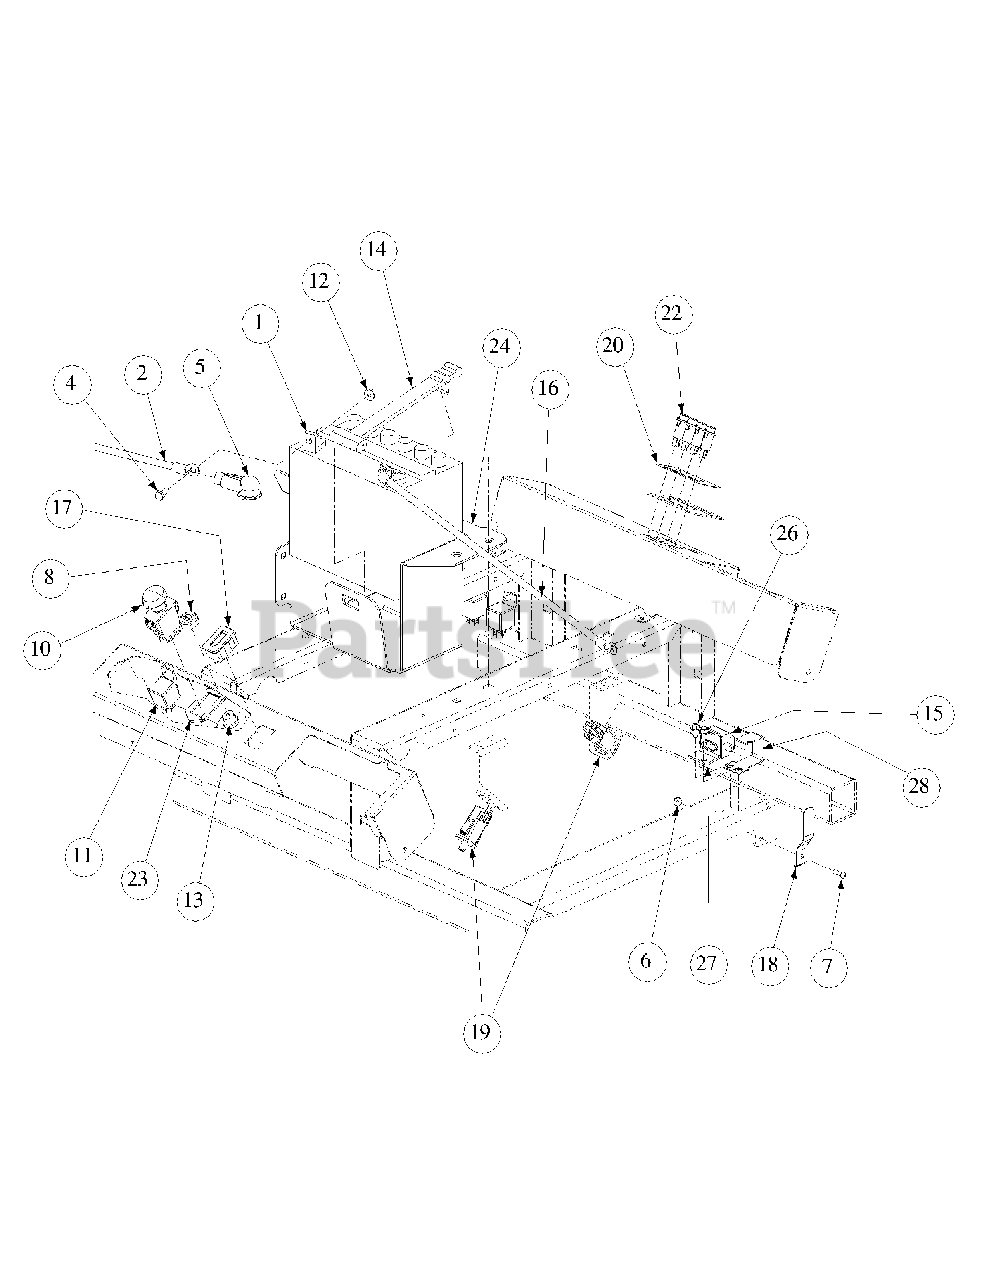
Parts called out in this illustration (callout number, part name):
1	Battery, 12V 225CCA 30 Min
2	Cable, Battery, Red, 36"
3	Tie, Cable, 3/16 x .05 x 7.4"
4	Screw, Hex, Cap, 1/4-20 x .75
5	Boot, 1" OD Rubber Battery-PST, Red
6	Nut, Lock, Nylon Insert, #10-32
7	Screw, Phillips Head, Machine, 10-32 x 5/8
8	Nut, W/Cap, 5/8-32 Ignition
9	Hourmeter, Harness
10	Switch, Electric, PTO
11	Relay, 12V 40A
12	Hex Flange Lock Nut, 1/4-20
13	Switch, Ignition, 6 Pin
14	Strap, Battery
15	Switch, Plunger
16	Cable, Battery Black, 34"
17	Meter, Hour
18	Spring Retainer
19	Neutral Switch
20	Decal, Engine Light
21	Harness Assembly
22	Light Indicator, 12V
23	Bracket, PTO Switch Retainer
24	Mount Bracket, Battery
26	Self Tapping Screw, 1/4-20 x .50
27	Bracket, Plunger Switch
28	Clamp, Plunger Switch
